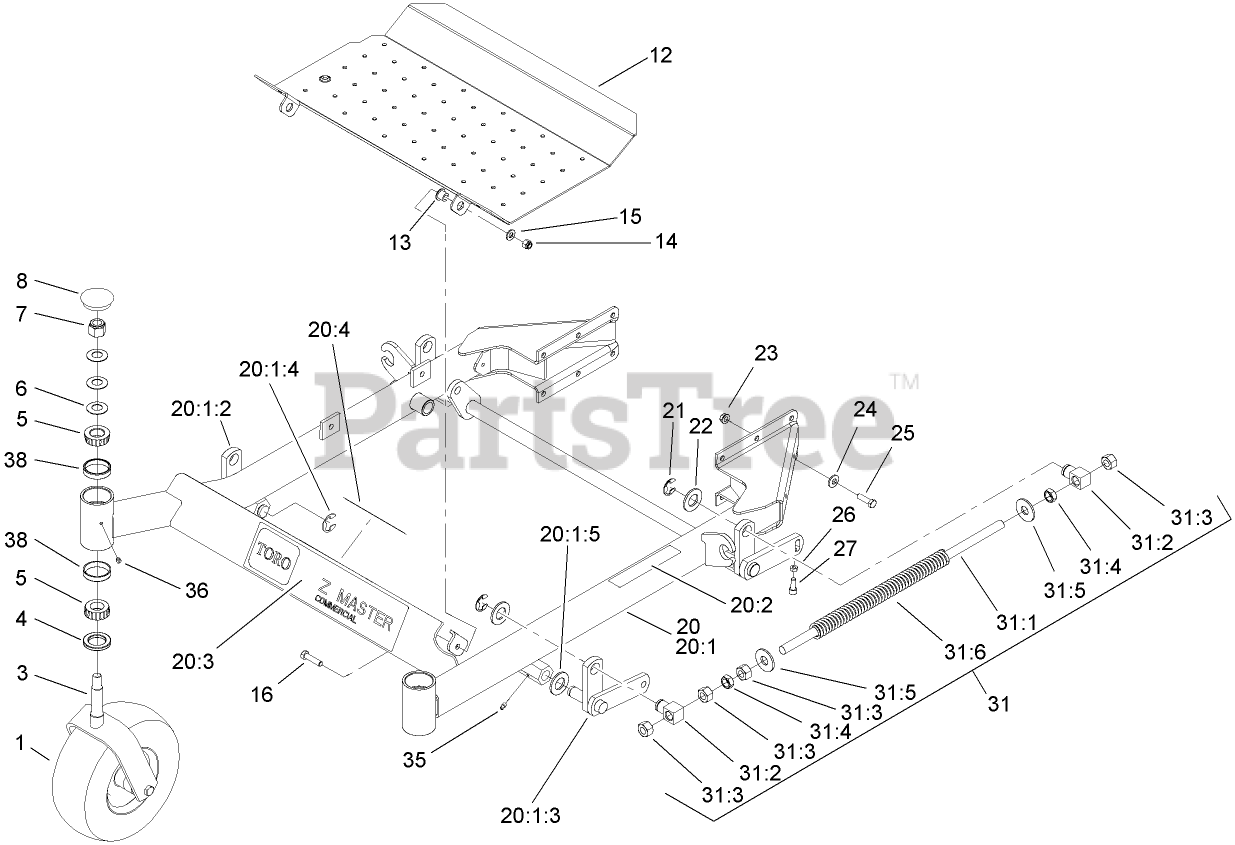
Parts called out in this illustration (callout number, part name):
1	SEMI PNUEMATIC WHEEL ASM
3	CASTER
4	SEAL-GREASE
5	BEARING-CONE, TAPERED
6	WASHER-BELLVILLE
7	NUT-LOCK, NI
8	CAP-GREASE
12	FLOOR PAN
13	BUSHING-FLANGE
14	NUT-LOCK, NI
15	WASHER-FLAT
16	SCREW-HH
20	FRONT FRAME ASM
20:1	FRAME-FRONT
20:1:2	RH LIFT ARM ASM
20:1:3	LH LIFT ARM ASM
20:1:4	RING-RETAINING, EXT
20:1:5	WASHER-FLAT
20:2	DECAL-WARNING
20:4	DECAL-WARNING
21	RING-RETAINING, EXT
22	WASHER-FLAT
23	NUT-HHF, WHIZ
24	WASHER-BELLEVILLE
25	SCREW-HH
26	NUT-JAM
27	SCREW-HSH
31	FRONT FRAME SPRING ASM
31:1	ROD-LIFT, DECK
31:2	SWIVEL-DECK MOUNT, REAR
31:3	NUT-HEX
31:4	NUT-JAM
31:5	WASHER-FLAT
31:6	SPRING-SUPPORT, DECK
35	FITTING-GREASE
38	BEARING-CUP, TAPERED
